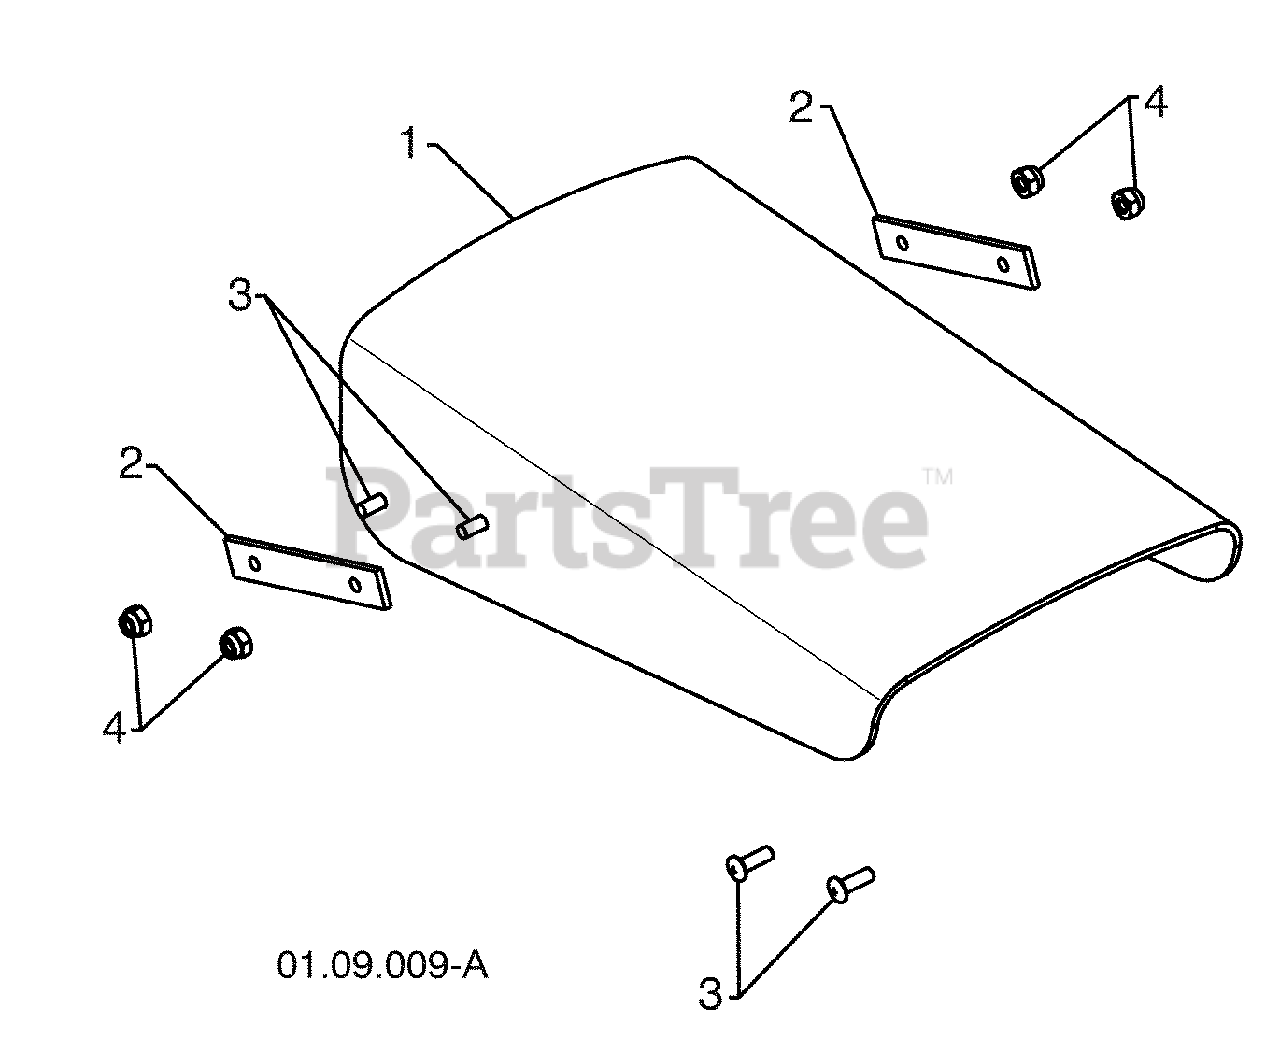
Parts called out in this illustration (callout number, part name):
1	SHIELD DEFLECTOR
2	STRAP
3	SCREW 8-32 X .50
